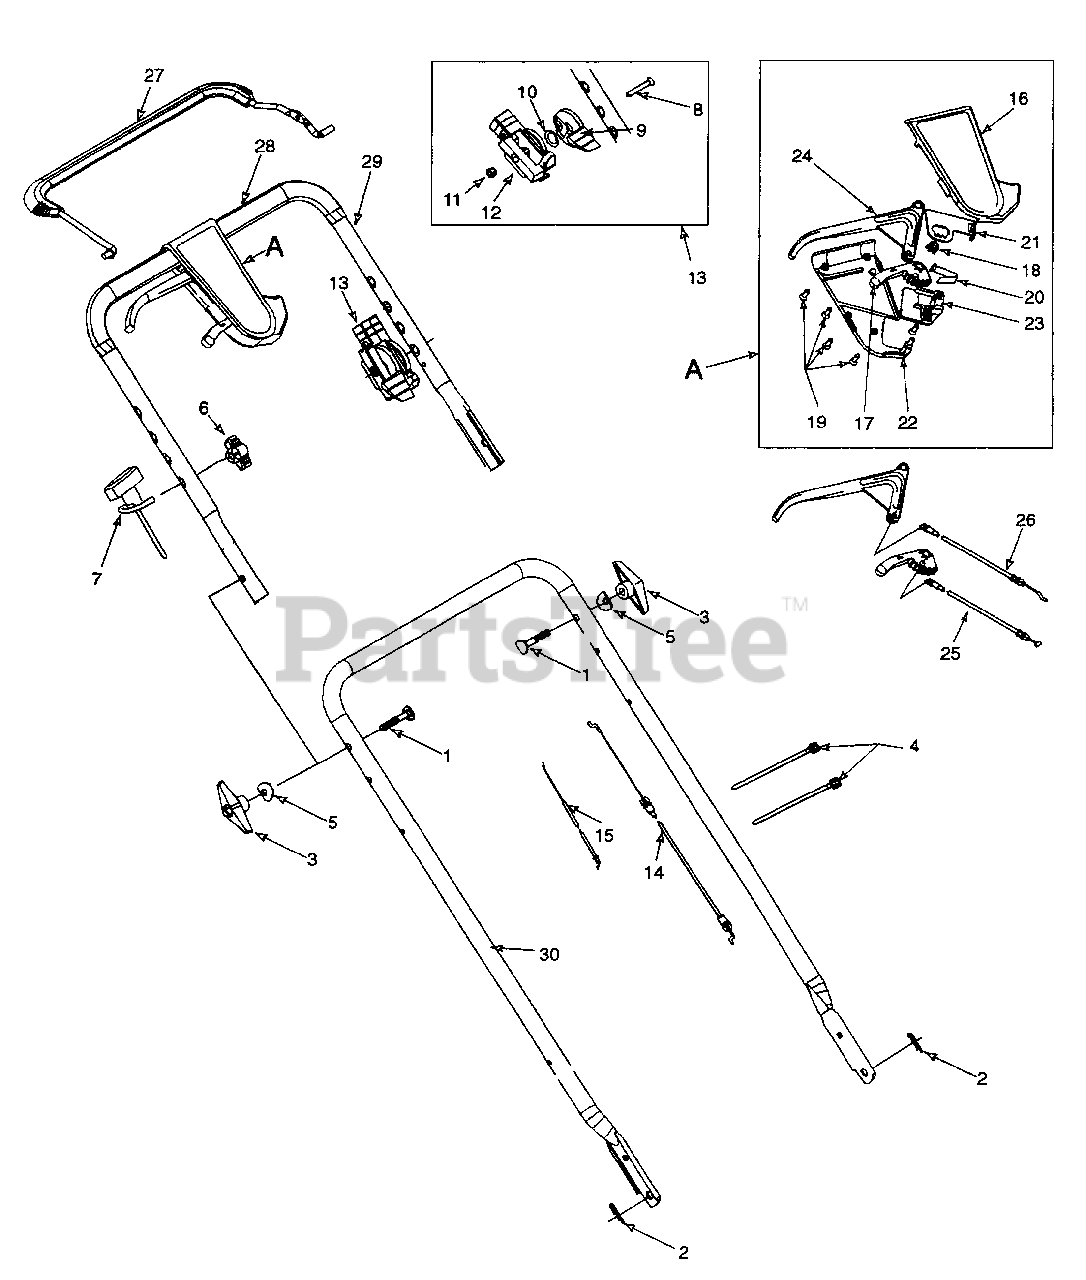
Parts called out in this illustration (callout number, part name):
1	Bolt Cur. Carr. 5/16-18 x 2" Lg.
2	Cotter Pin .072 x 1.12 Lg.
3	Knob Ass'y Wingnut 5/16-18
4	Strap 4.3 Lg.
5	Wash. Sad. .320 ID x .830 OD
6	Knob Handle ERS - 1/4-20
7	Rope Guide Eyebolt
8	Screw 1/4-20 x 1.81
9	Throttle Lever
10	Spring Wash. Curved
11	Nut 1/4-20 Top locknut Insert
12	Housing, Throttle
13	Throttle Control
14	Control Cable 44" Lg.
15	Cable Throttle 60" Lg.
16	Upper Control Housing
17	6 Speed Shift Lever
18	Gear Insert
19	C-Sunk Tap Scr. #10 x .75" Lg.
20	Shift Lever Spring
21	6 Spd. Rack Cable Brkt.
22	Lower Control Housing
23	Cable Mounting Cap
24	Control Lever
25	6 Spd. Cable
26	S.P. Cable
27	Control Handle
28	Foam Grip
